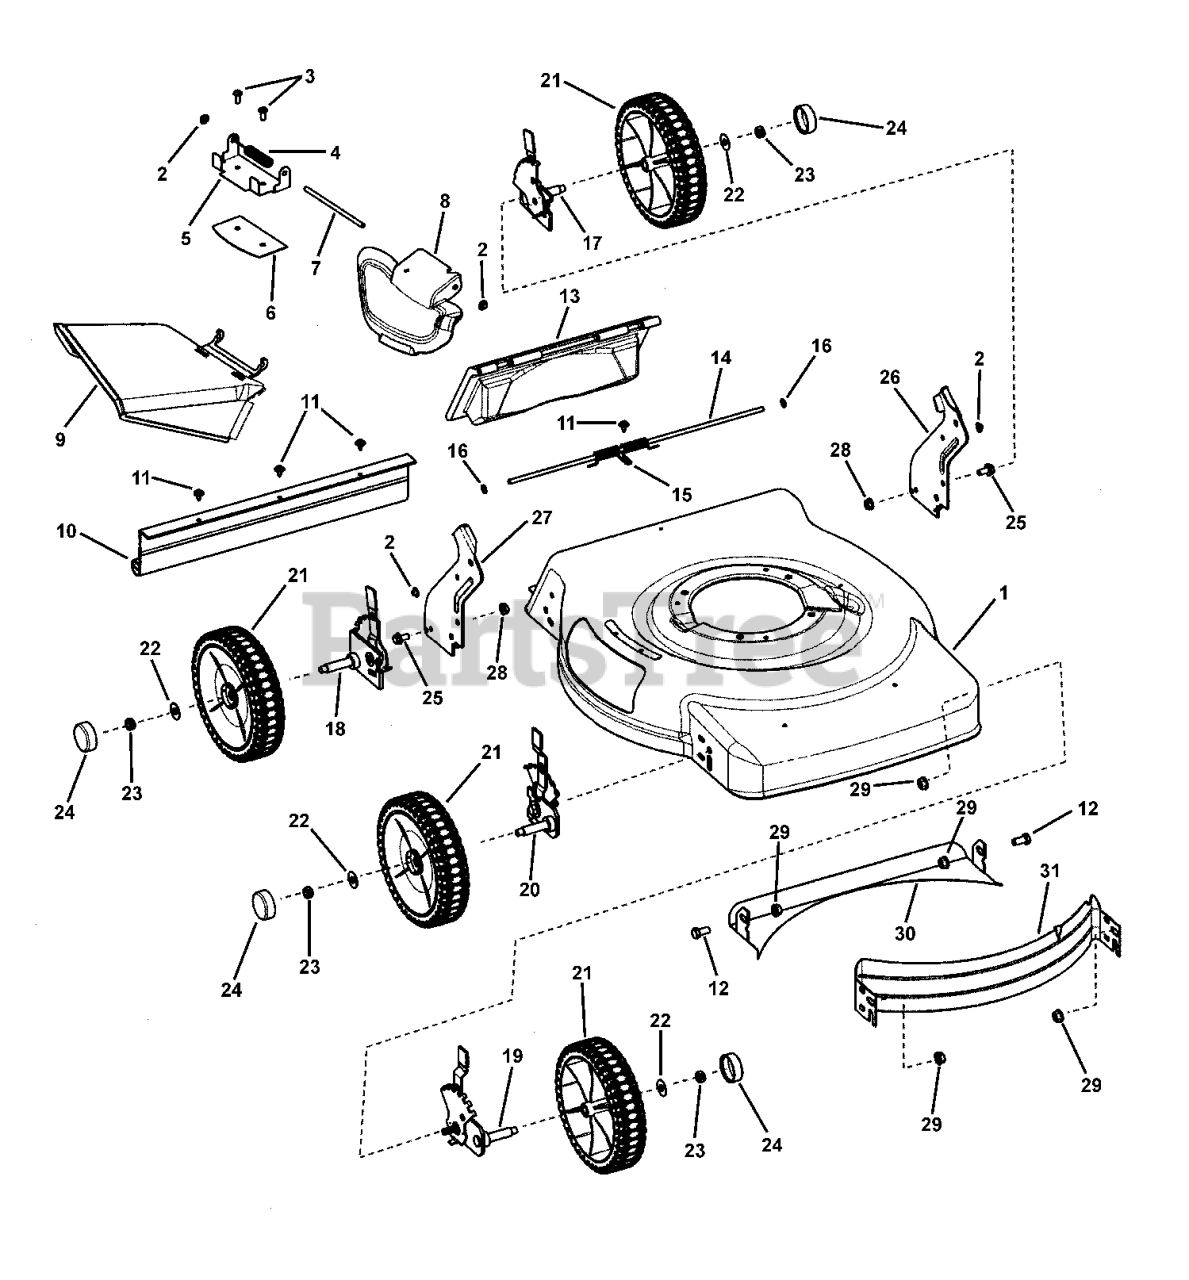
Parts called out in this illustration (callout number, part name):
1	DECK, 22" Walk, Push 3-N-1
2	PUSHNUT, 1/4"
3	SCREW, 1/4-20 x 11/16" Pan Head Self-Tap - Torx
4	SPRING, Chute - Torsion
5	BRACKET, Chute
6	PLATE, Mulch, 22" RB Scott's
7	ROD, Chute Pivot - 1/4" Dia. x 5.55"
8	COVER, Mulch, Plastic, Black
9	SIDE CHUTE, Plastic, Black
10	GUARD, Rear
11	SCREW, #10-24 x 1/2" Hex Washer Self-Tap - Sems
12	SCREW, 3/8-16 x 3/4" Hex Head Cap, GR 5
13	DOOR, Rear Discharge, 22" Walk Mower
14	ROD, Pivot, Rear Door - 1/4" Dia. X 17-1/2"
15	SPRING, Torsion, Rear Door, 22" Walk Mower
16	CAP, Retainer
17	ASSY, Height-of-Cut, Left Rear, 7 Position
18	ASSY, Height-of-Cut, Right Rear, 7 Position
19	ASSY, Height-of-Cut, Left Front, 7 Position
20	ASSY, Height-of-Cut, Right Front, 7 Position
21	ASSY, Wheel, 8"x 2" Idle, NB Murray Tread, Gray
22	WASHER, 1" O.D. x .387 I.D. Flat
23	NUT, 3/8-16 Hex Center Lock, YZ
24	HUBCAP, Round, Black
25	BOLT, 5/16-18 x 5/8" Hex Flange Lock, GR 5 YZ
26	BRACKET, Lower Handle, RH
27	BRACKET, Lower Handle, LH
28	NUT, 5/16-18 Flange Lock, YZ
29	NUT, 3/8-16 Hex Flange Lock, GR 5
30	BAFFLE, Rear, 22" Deck
31	BAFFLE, Front, 22" WBM
